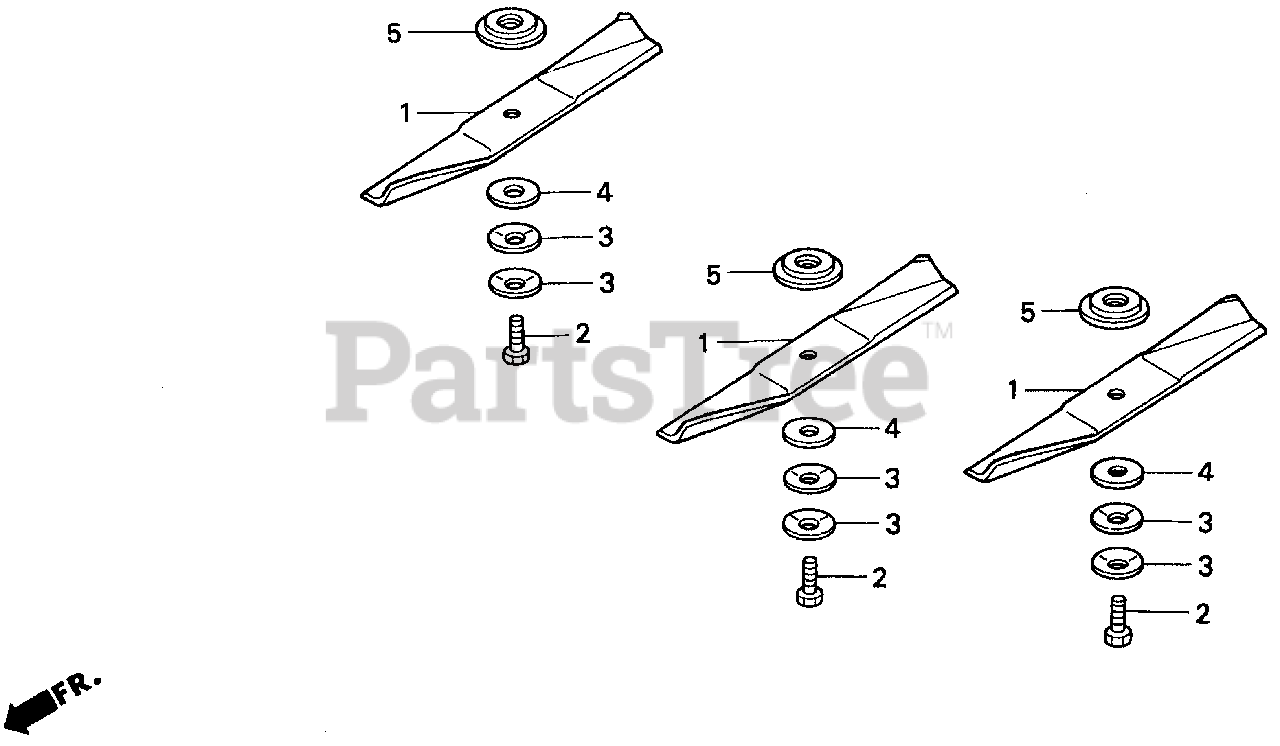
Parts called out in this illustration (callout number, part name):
1	BLADE, ROTARY
2	BOLT (5/8 NCX2 HHCS)
3	WASHER, CUP (5/8X1-3/4X14)
4	WASHER, FLAT (5/8)
5	WASHER, SHOULDER
